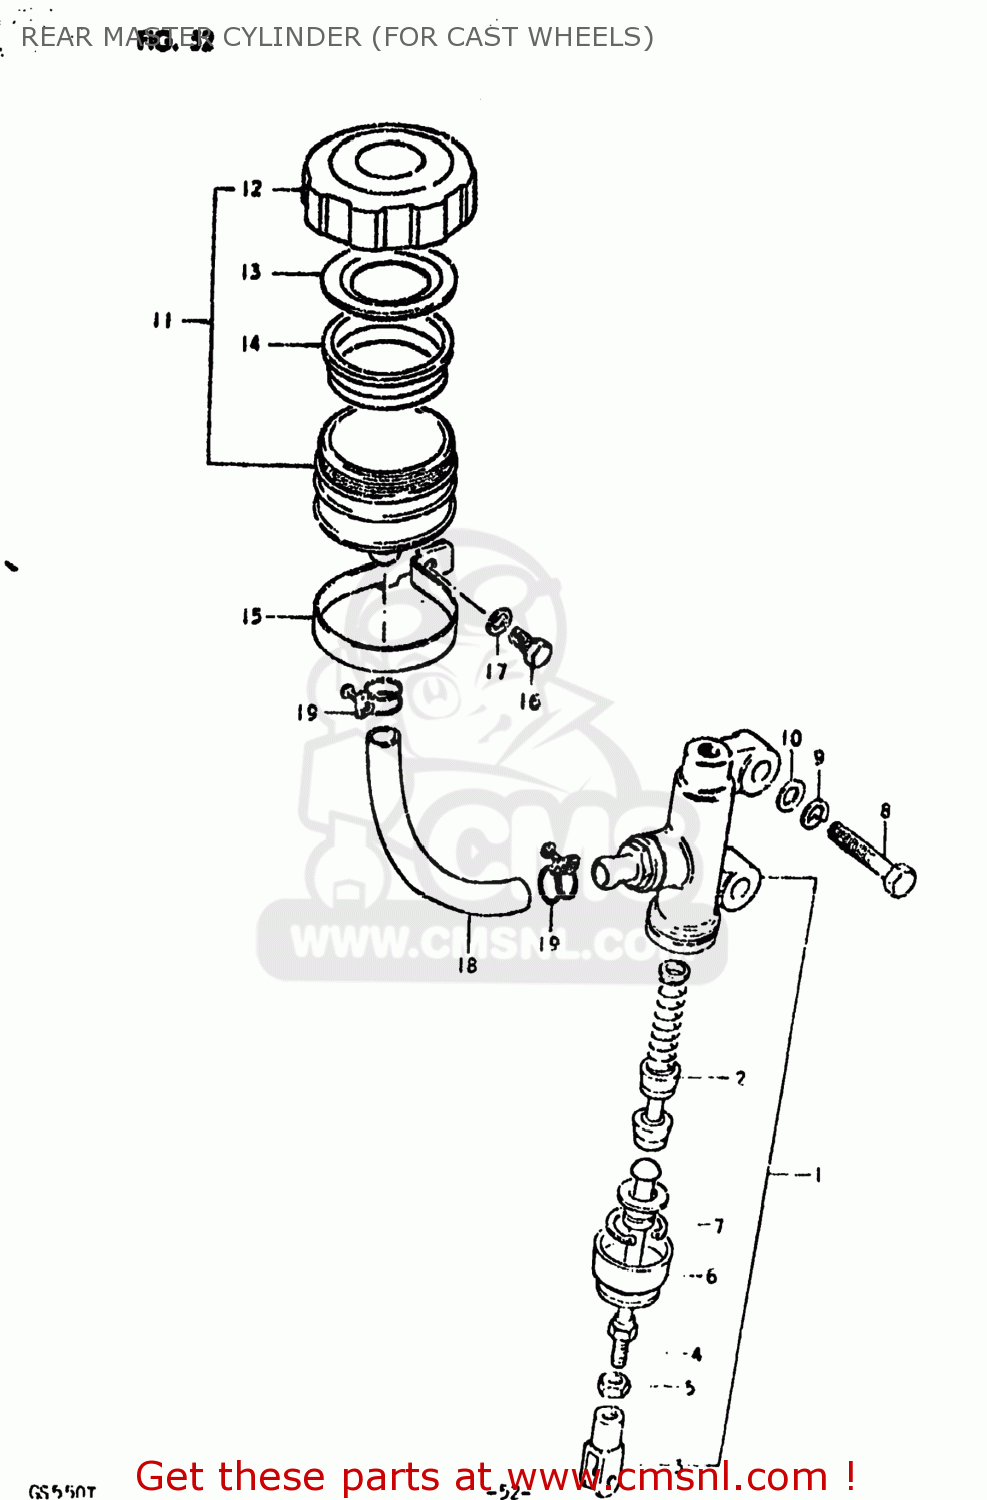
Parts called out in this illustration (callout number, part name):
1	CYLINDER ASSEMBLY,REAR MASTER
2	PISTON/CUP SET
3	YOKE
4	ROD,PUSH
5	NUT
6	BOOT
7	CIRCLIP
8	BOLT (8X30)
9	LOCK WASHER
10	WASHER
11	TANK ASSEMBLY,RESERVOIR
12	CAP
13	PLATE,DIAPHRAGM
14	DIAPHRAGM
15	CLAMP
16	BOLT, UPPER
17	LOCK WASHER
18	HOSE,RESERVOIR TANK
19	CLAMP
